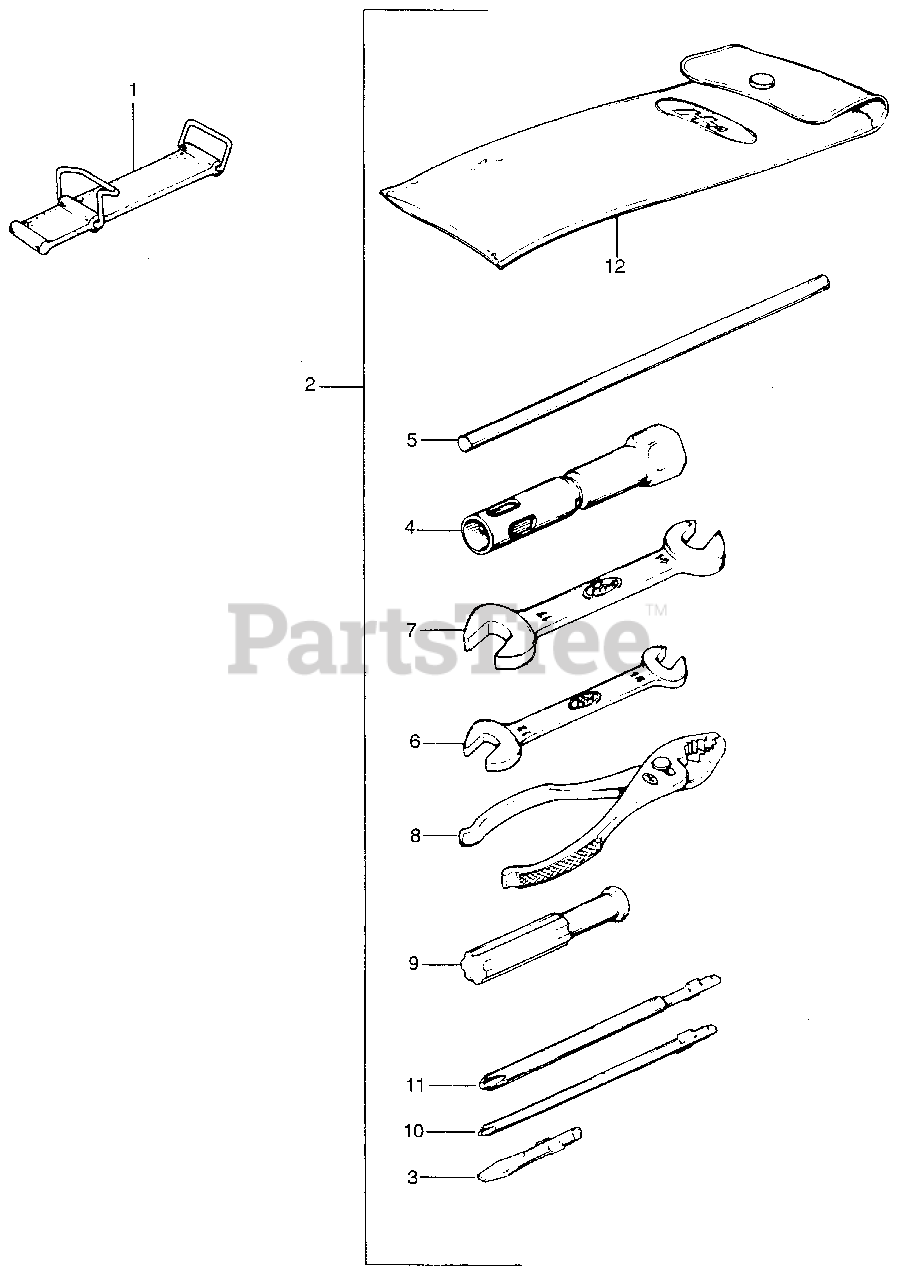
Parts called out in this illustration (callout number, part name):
1	STRAP, TOOL BAG RETAINING (NOT AVAILABLE)
2	TOOL ASSY.
3	SCREWDRIVER, SPECIAL
4	WRENCH, SPARK PLUG (NOT AVAILABLE)
5	SHAFT, WRENCH (KOWA)
6	WRENCH (10X12) (OPEN END)
7	WRENCH (14X17) (OPEN END)
8	PLIERS (135MM)
10	SCREWDRIVER 1, PHILLIPS (NO.2)
11	DRIVER 2, PHILLIPS SCREW (NO.3)
12	BAG, TOOL
